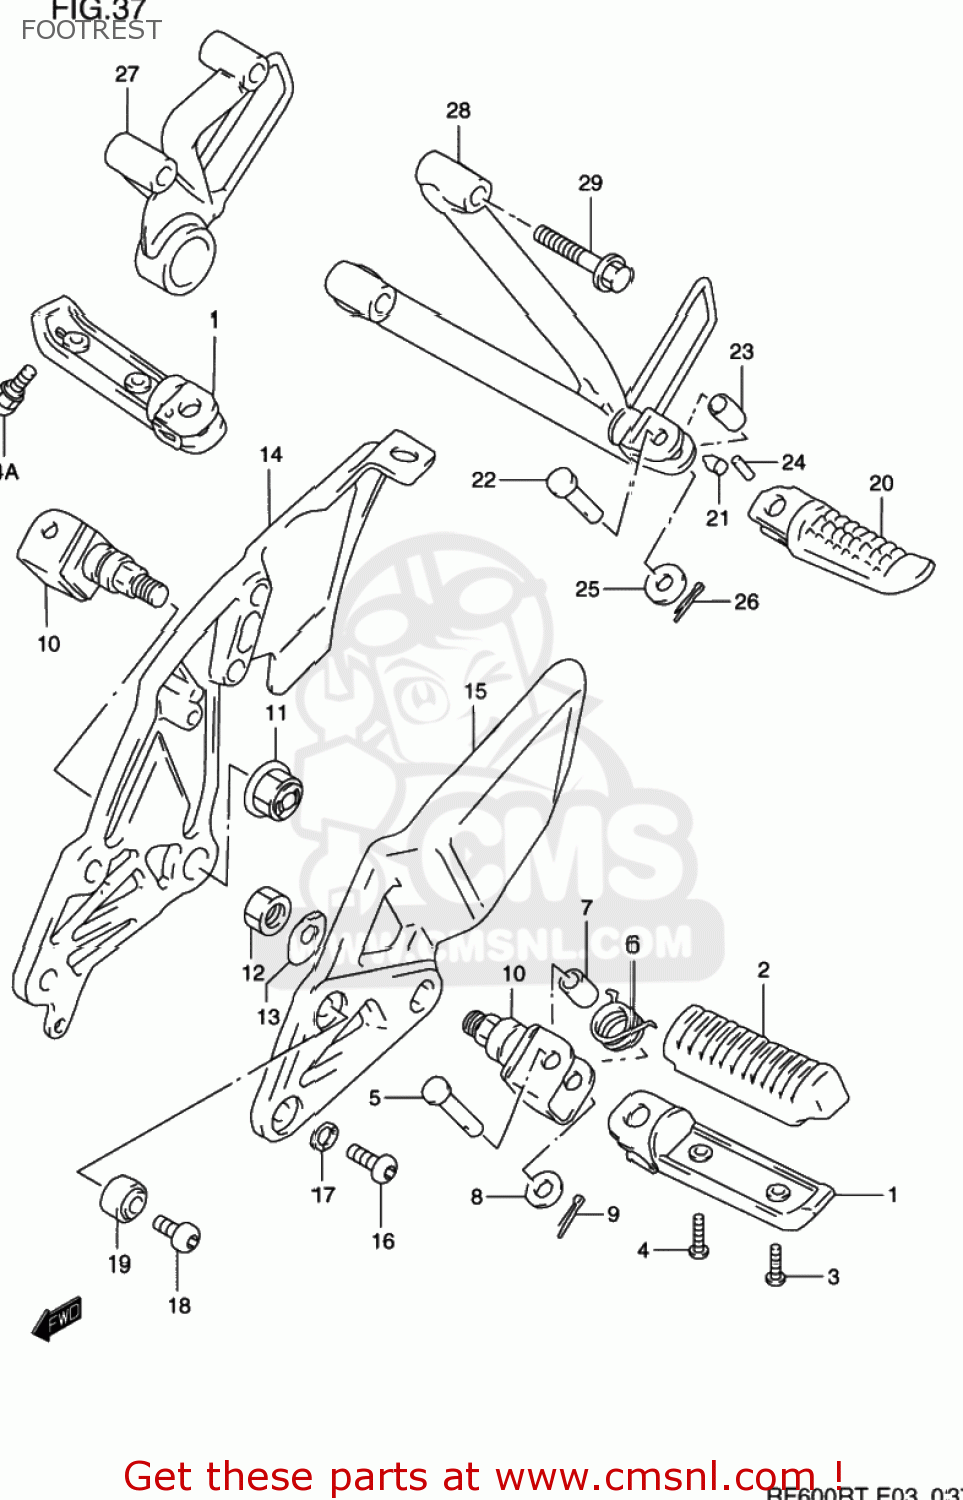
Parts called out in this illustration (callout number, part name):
1	BAR,FOOTREST,R
2	RUBBER,FOOTREST
3	SCREW
4	SCREW
4A	SENSOR,FOOTREST
5	PIN
6	SPRING
7	SPACER(8.1X12X22)
8	WASHER(8.5X18X1)
9	PIN 20X15
10	BOSS,FR FOOTREST
11	NUT 12MM
12	NUT
13	WASHER,FR FOOTREST
14	BRACKET,FOOTREST,R
15	BRACKET,FOOTREST,L
16	BOLT
17	WASHER
18	BOLT(8X25)
19	BUSH
20	BAR,PILLION FOOTREST R
21	CUSHION,FOOTREST HOLDER
22	PIN
23	SPACER(8.1X12X22)
24	PIN(4X20)
25	WASHER
26	PIN 20X15
27	BRACKET,PILLION FOOTREST
28	BRACKET
29	BOLT
